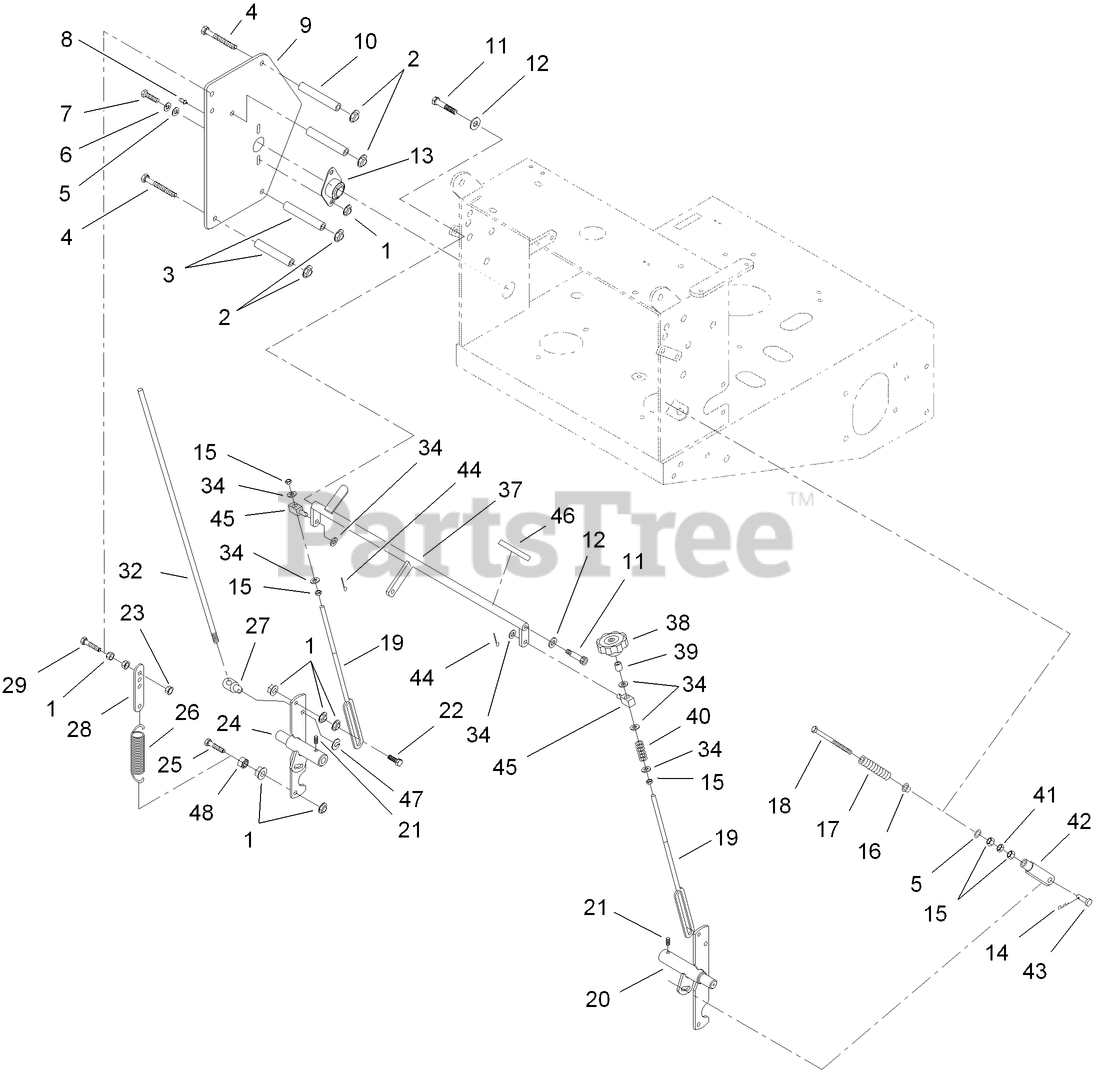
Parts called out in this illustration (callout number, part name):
1	NUT-HF
2	NUT-HHF, WHIZ
3	SPACER-SHIELD
4	SCREW-HH
5	WASHER-FLAT
6	WASHER-LOCK
7	SCREW-HH
8	FITTING-GREASE
9	SHIELD-CONTROL
10	Spacer-Shield
11	SCREW-HSH
12	WASHER-FLAT
13	BEARING-FLANGE, SIDE
14	PIN-COTTER
15	NUT-HEX
16	BUSHING-NYLON, FLANGED
17	SPRING-RETURN, NEUTRAL
18	BOLT-RETURN, NEUTRAL
19	LINK-CONTROL, SPEED
20	SHAFT-CONTROL, RH
21	SCREW-SET
22	SCREW-HH
23	NUT-LOCK, NI
24	Shaft-Control, LH
25	SCREW-HH
26	SPRING-EXTENSION
27	SWIVEL-LEVER, DRIVE
28	TAB-SPRING, EXTENSION
29	BOLT-TAP, HH
32	ROD-LEVER, DRIVE
34	WASHER-PLAIN
37	Crank-Control, Speed
38	KNOB-TRACKING
39	SPACER
40	SPRING-COMPRESSION
41	NUT-JAM
42	YOKE-ADJUSTABLE
43	PIN-CLEVIS
44	PIN-COTTER
45	SWIVEL-ADJUSTABLE, SHORT
46	DECAL-TRACKING
47	RING-RETAINING
48	NUT-JAM
